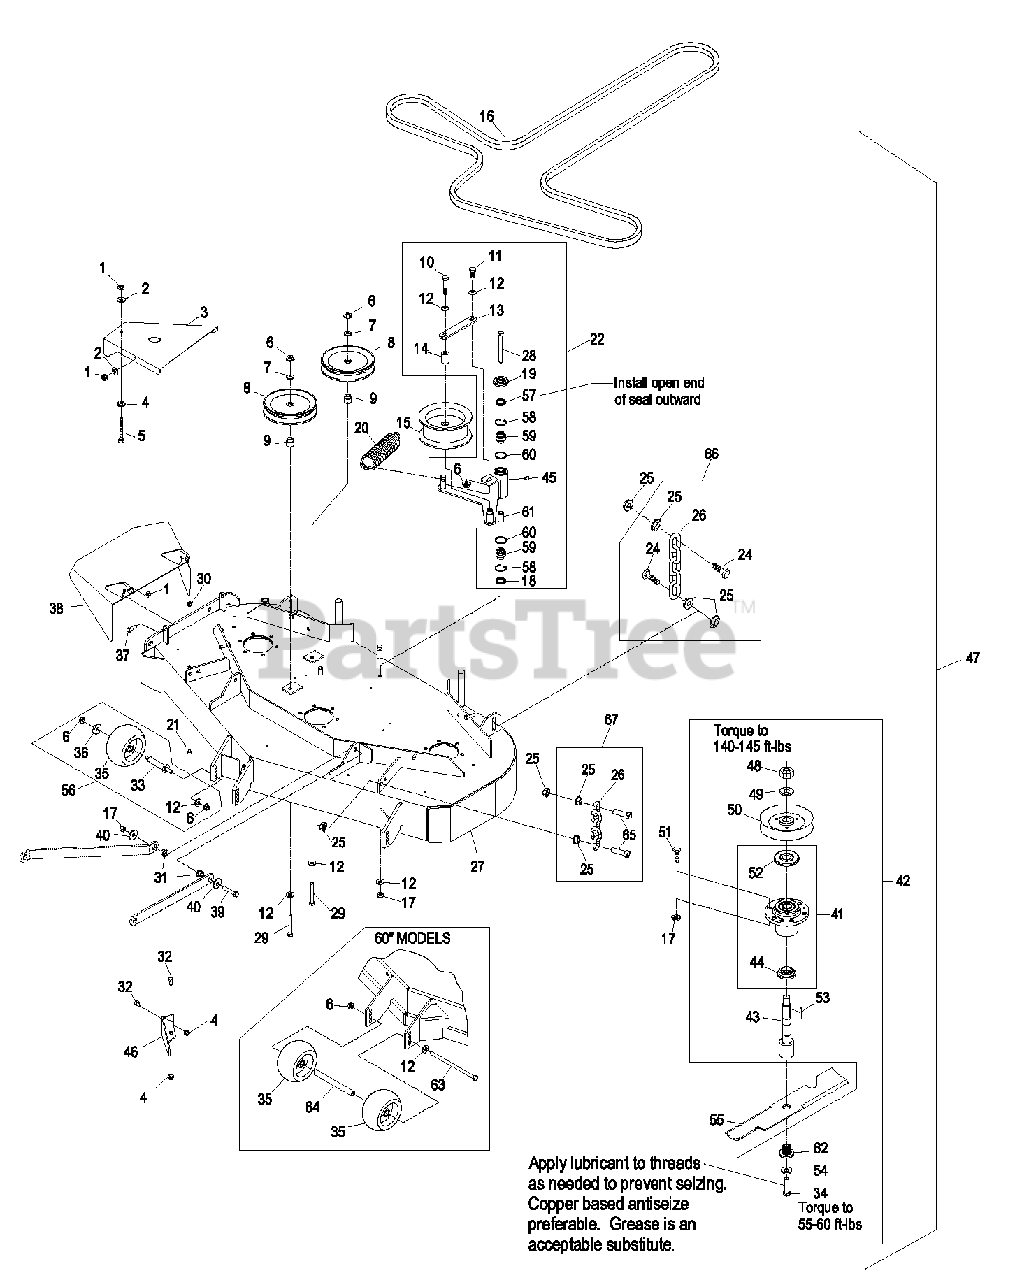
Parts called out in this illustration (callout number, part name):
1	NUT-LOCK, NI
2	WASHER-FLAT
3	BELT SHIELD W/ DECAL
5	BOLT,TAP HH
6	NUT-HHF, WHIZ
7	WASHER-FLAT
8	PULLEY-IDLER
9	BUSHING-IDLER
10	SCREW-HH
11	SCREW-HH
12	WASHER-BELLEVILLE
13	PLATE,GUIDE BELT (PLTD)
16	BELT,DECK DRIVE
16	BELT,BLADE DRIVE
16	BELT-B162.50
17	NUT-LOCK, NI
18	SEAL-LIP, DOUBLE
19	GUARD-TOP
21	SCREW-HH
22	KIT,DECK IDLER LHP/LCT
23	BUSHING-PIVOT, IDLER
24	SCREW-CAP, HH
26	CHAIN-LIFT, DECK
27	ASM,DECK W/DECALS LCT48
27	ASM,DECK W/ DECALS LCT52
27	ASM, DECK W/DECALS
28	SCREW-HH
29	SCREW-HH
31	SPACER-STRUT
32	SCREW-HH
34	SCREW-HH
35	ROLLER-SCALP, ANTI
37	SCREW-HH
38	WLD,CHUTE 48
38	WLD,DISCHARGE CHUTE
39	SCREW-HH
41	KIT, CUTTER HOUSING
42	ASM, CUTTER HSG
42	ASM, CUTTER HSG 52
42	ASM, CUTTER HOUSING COMPL
43	KIT, SPLINED SPINDLE 103-
44	SPACER-GUARD, BOTTOM
45	FITTING-GREASE, 90 DEG
46	WLD,BAFFLE DISCHARGE
47	Asm, Deck Complete (48")
47	Asm, Deck Complete (52")
47	Asm, Deck Complete (60")
48	NUT-HH
50	SHEAVE,W/HUB 5.72
50	SHEAVE,6.13 EOD
50	SHEAVE, DECK
51	SCREW-HH
52	GUARD-BEARING, TOP
53	KEY-RECTANGLE
54	WASHER-SPRING
57	SEAL-LIP, SINGLE
58	RING-SNAP
59	BEARING-SPHERICAL
62	BUSHING,SPLINED
63	SCREW-HH
64	SPACER-WHEEL
65	SCREW-HH
66	DECK CHAIN ASM
67	DECK CHAIN ASM
